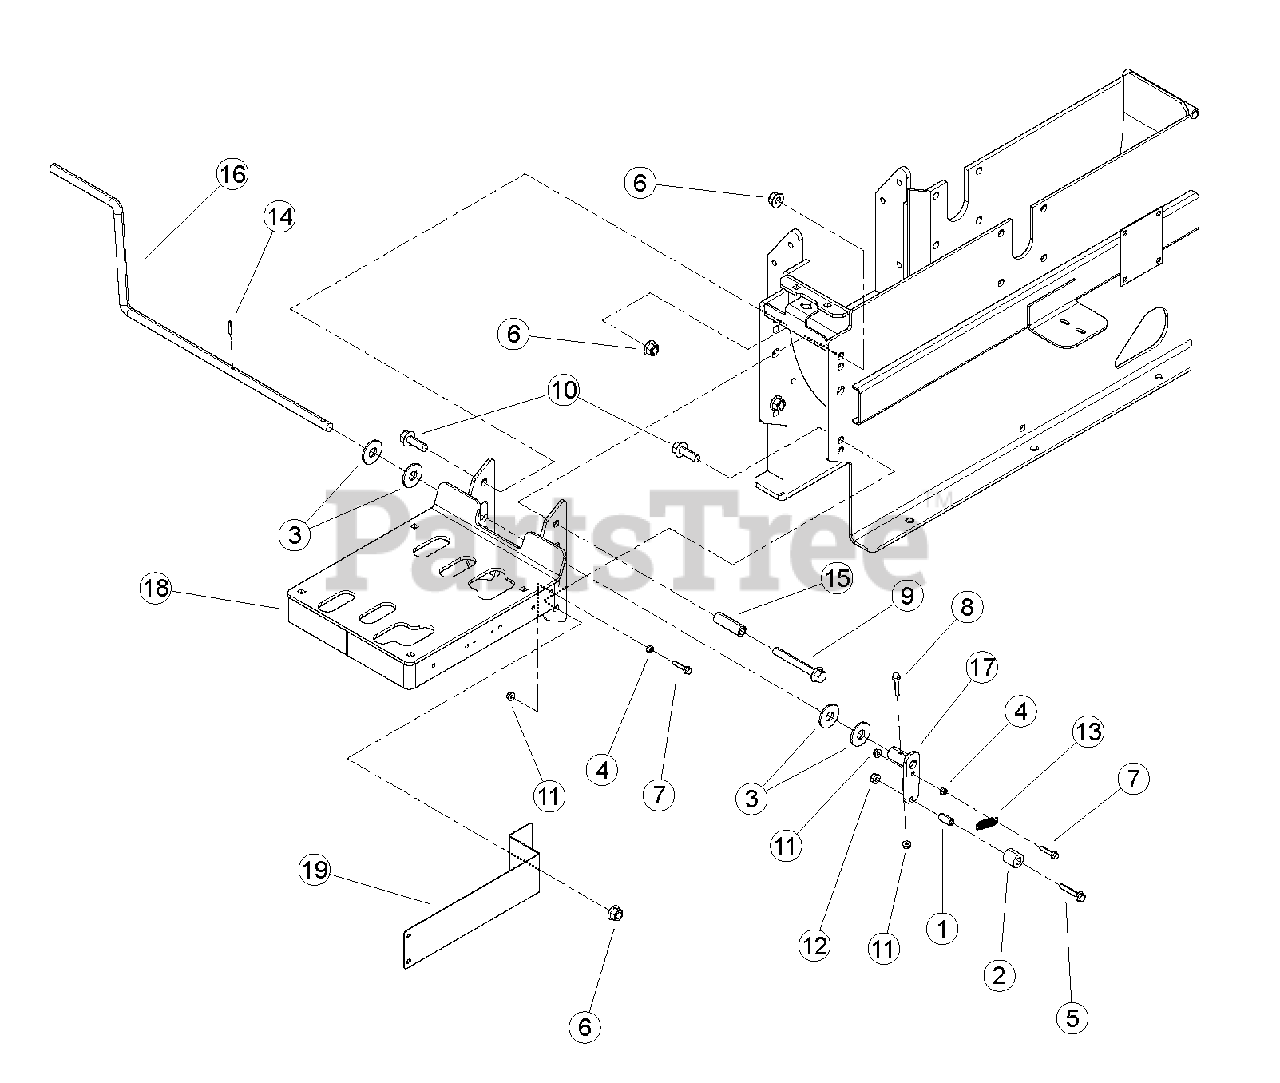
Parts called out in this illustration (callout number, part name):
1	SPACER, 0.5 X 1.00
2	ROLLER, 0.5 X 1.00 X 1.00 NYLON
3	WASHER, 5/8" FLAT ZP
4	NUT, 1/4"-20 SERRATED FLANGE NC ZP
5	BOLT, 5/16 X 1-3/4 FLANGE NC
6	NUT, 1/2-13 NYLOCK FLANGE
7	BOLT, 1/4 X 1-1/4 FLANGE NC
8	BOLT, 1/4 X 1-1/2 FLANGE NC
9	BOLT, 1/2-13 X 4 HWH GR5 CZP
10	BOLT, 1/2-13 X 1-1/2 GR5 FLANGE NC
11	NUT, 1/4-20 NYLOCK-FLANGE
12	NUT, 5/16-18 NYLOCK-FLANGE
13	SPRING, 1/2 X 2.00 LG, ZP
14	PIN, ROLL 3/16 X 1"
15	SPACER, .75 X 2.06
16	HANDLE, ENGAGEMENT
17	WELDMENT, SHAFT ENGAGEMENT ARM
18	WELDMENT, ENGINE BASE
19	SHIELD, HYD PUMP
